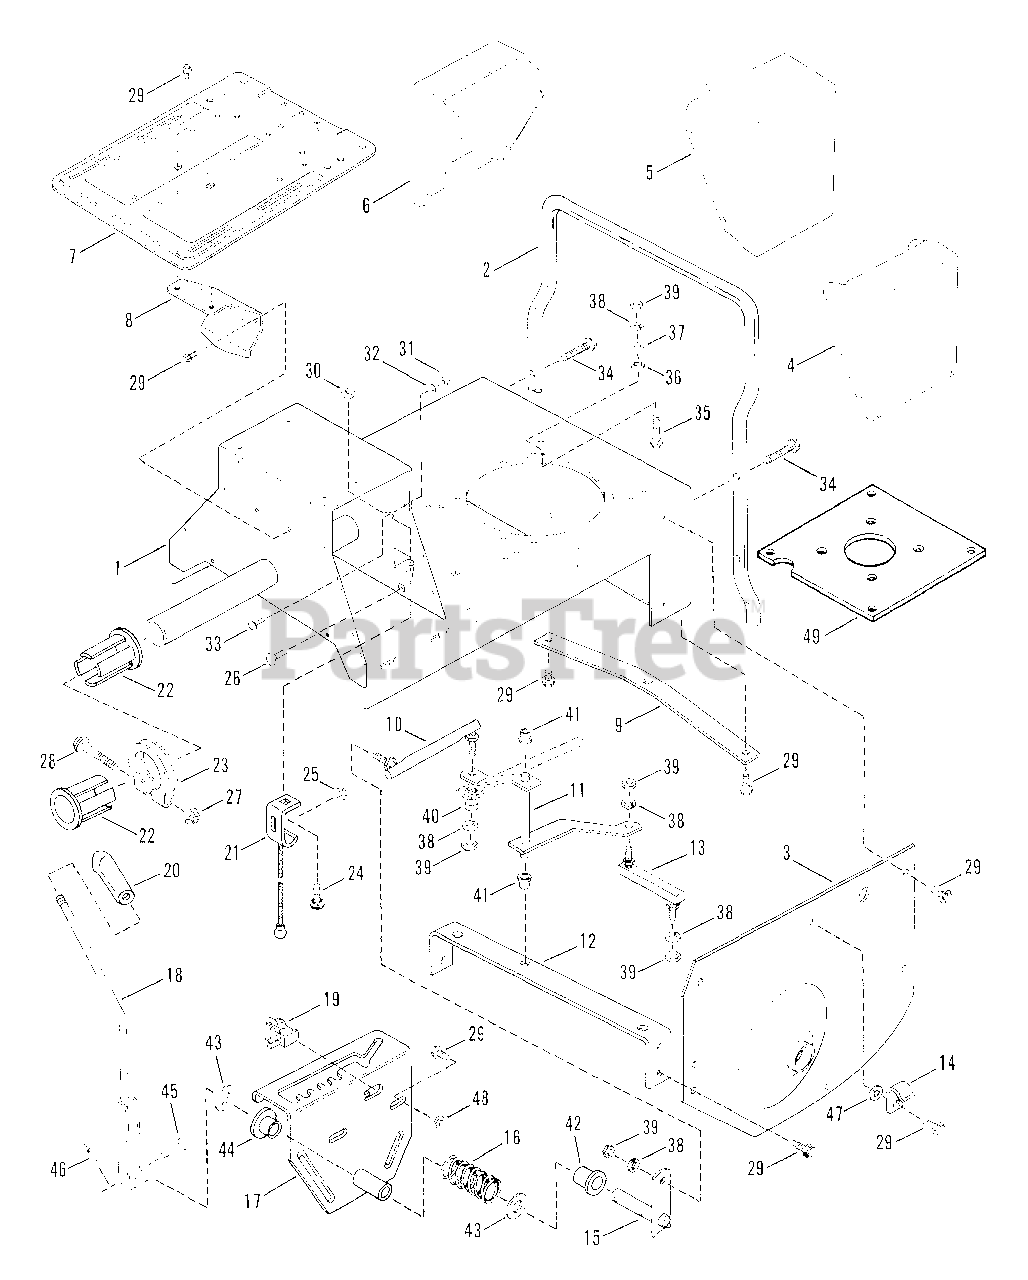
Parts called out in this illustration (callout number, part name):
1	MAIN CASE
2	BUMPER, Rear
3	FENDER, Left Hand
4	COVER
5	COVER, Battery
6	COVER, Switch
7	BASE, Seat Support
9	PLATE, Hitch
10	LINK, Shift, Long
11	ARM, Shift
12	BRACE, Cross
13	LINK, Shift, Short
14	CLIP, Wiring
15	ARM, Shift Handle
16	SPRING, Shift Handle
17	DETENT, Shift
18	HANDLE, Shift
19	SWITCH, Seat
20	KNOB, Shift Handle
21	CABLE, Deck Support
22	BUSHING, Main Tube
23	CLAMP, Main Tube
24	BOLT, 5/16-18 x 1-1/2" Carriage
25	NUT, 5/16-18 hex Flange Lock
26	BOLT, 5/16-18 x 5/8" Short Neck Carriage
27	NUT, 5/16-24 Hex Flange Lock
28	SCREW, 5/16-24 x 2-1/2" hex head Cap
29	SCREW, 5/16-18 x 5/8" Self-Tapping
30	NUT, 5/16-18 Hex Flange Lock
31	WING-NUT, #10-24 Locking
32	RETAINER, Bolt
33	BOLT, #10-24 x 1/2" carriage
34	SCREW, 5/16-18 x 1-1/2" self-Tapping
35	SCREW, 5/16-24 x 1-1/2" Hex Head Cap
36	RETAINER, Bolt
37	WASHER, 5/16" Flat
38	WASHER, 5/16" Split Lock
39	NUT, 5/16-24 Hex
40	ROLLER
41	BUSHING, Nylon
42	BUSHING, Nylon
43	WASHER, Thrust
44	BUSHING, Nylon
45	CLEVIS-PIN
46	COTTER-PIN, 3/32 x 3/4"
47	WASHER, 5/16 Internal Tooth Lock
48	NUT, 5/16-18 Hex
49	ENGINE PLATE, 14 HP Briggs Vanguard
